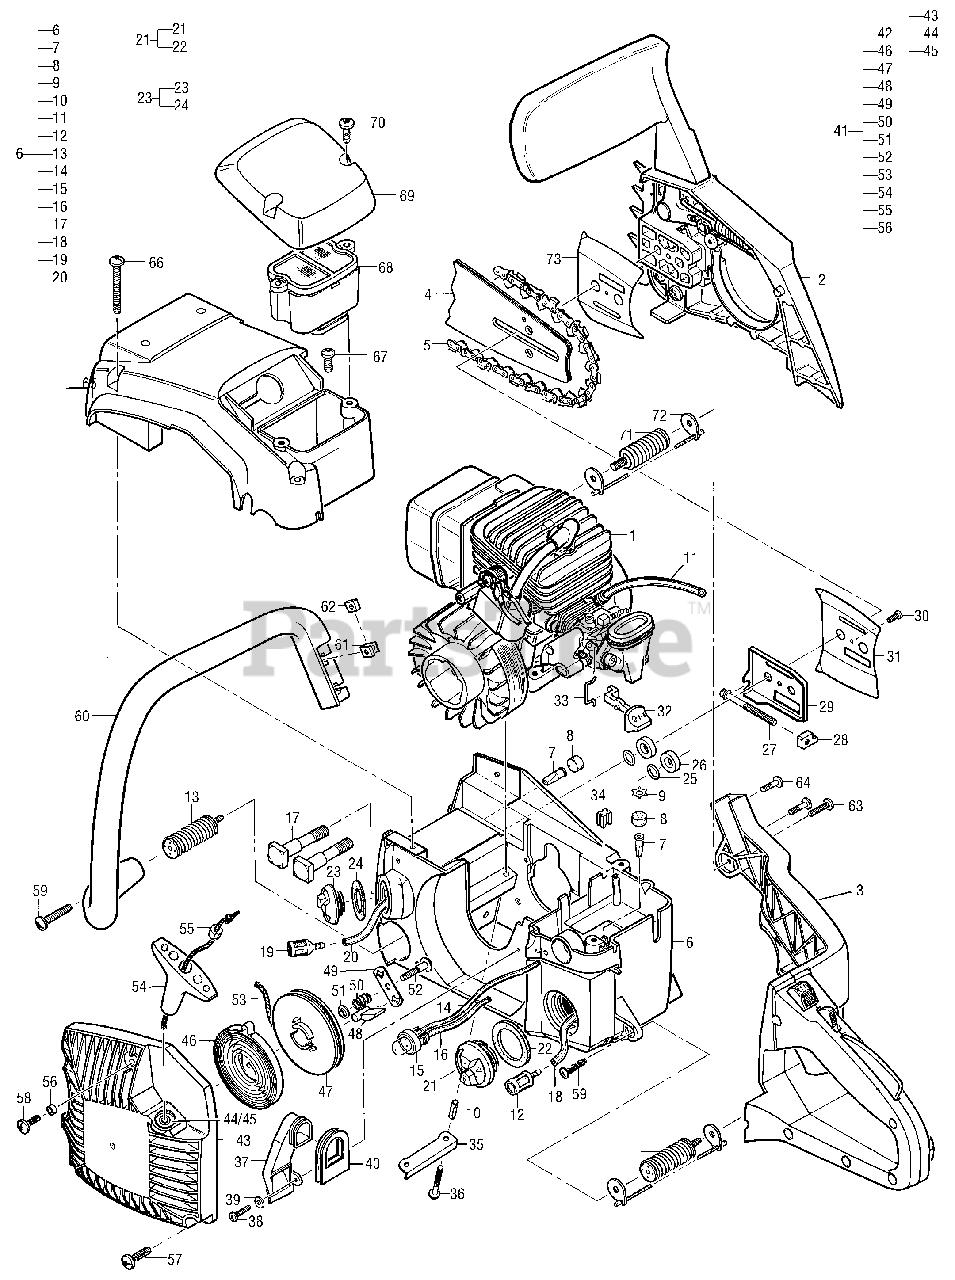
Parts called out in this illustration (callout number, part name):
1	Powerhead Asy
2	Chain Brake Asy
3	Rear Handle Asy
4	Bar Information
5	Chain Information
6	Fuel/Oil Tank Asy (Black)
7	Valve, Duckbill
8	Filter, Foam
9	Retainer, Vent
11	Hose, Pulse
12	Pickup, Fuel
13	Isolator Asy Handle
14	Hose, Fuel
15	Primer, Remote
16	Hose, Primer
17	Bolt, Bar 5/16-18, Shoulder
18	Hose, Oil
19	Pickup, Oil
20	Hose, Fuel/Oil
21	Fuel Cap Asy
22	Gasket
23	Oil Cap Asy
24	Gasket, Oil Cap
25	O-Ring, .013
26	Washer, Bar Bolt
27	Bar Adj Screw Nut & Ring
28	Nut, Bar Adjusting
29	Plate, Bar
30	Screw, 6-19 x .375
31	Plate, Bar Guide
32	Lever, Choke
33	Rod, Choke
34	Plug, Pulse Hose
35	Plate, Flange
36	Screw, 10-24x1 Torx
37	Precleaner Asy
38	Screw, 8-16 Plast
39	Washer, #8 Plain
40	Boot, Intake
41	Starter Asy (Yellow)
42	Housing/Rope Guide Asy
43	Housing, Starter (Yellow)
44	Rope Guide
45	Tube, Rope Guide
46	Spring, Starter Rewind
47	Pulley, Starter
48	Pawl, Starter
49	Plate, Starter
50	Spring, Friction
51	Spacer, Starter
52	Screw, Shoulder
53	Rope, Starter 45"
54	Handle, Starter
55	Bushing, Starter
56	Spacer, 10x.135
57	Screw, 10-14x.625 Torx
58	Screw, 10-24x.5 Torx
59	Screw, 10-14x1.38 Torx
60	Handle, Front
61	Retainer, Nut
62	Nut, Sq 10-24
63	Screw, 10-14x1 Plast
64	Screw, 10-24x.5 Pn Hd Torx
65	Top Cover Asy (Black)
66	Screw, 10-14x2
67	Screw, 10-14 Torx Hd
68	Air Cleaner Asy
69	Cover, Air Cleaner (Black)
70	Screw, k10-24x.625 Pn Hd Torx
71	Isolator Asy
72	Cable Asy, AV Spring
73	Plate, Flange
